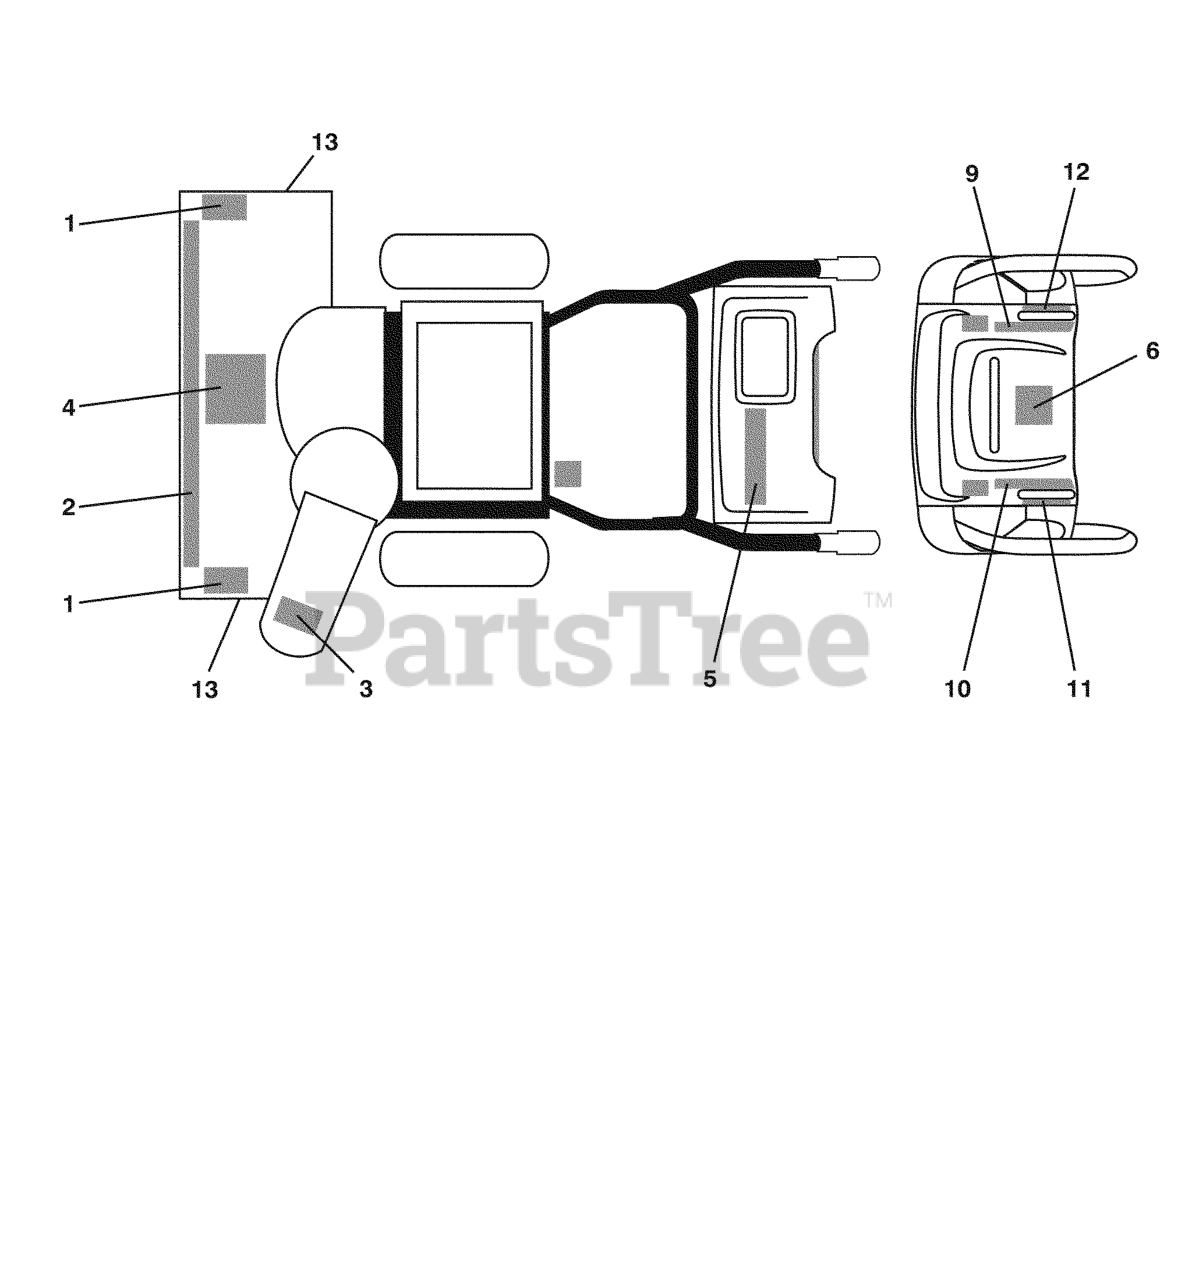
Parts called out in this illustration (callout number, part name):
1	DECAL.SNOWTHR.AUGER
2	DECAL.AUGER.HSG."HUSQVARNA"
3	DECAL.SNOWTHR.CHUTE.SAFETY
4	DECAL.SNOWTR.READ.OWN.MAN.E/F
5	DECAL.CONSOLE.PAN."HUS"1130SBE
6	DECAL, INSTRUCTION
9	DECAL SPEED CONTROL
10	DECAL, REMOTE DEFLECTOR
11	DECAL POWER STEER
12	3ECAL POWER STEER
13	DECAL, HUSQVARNA
